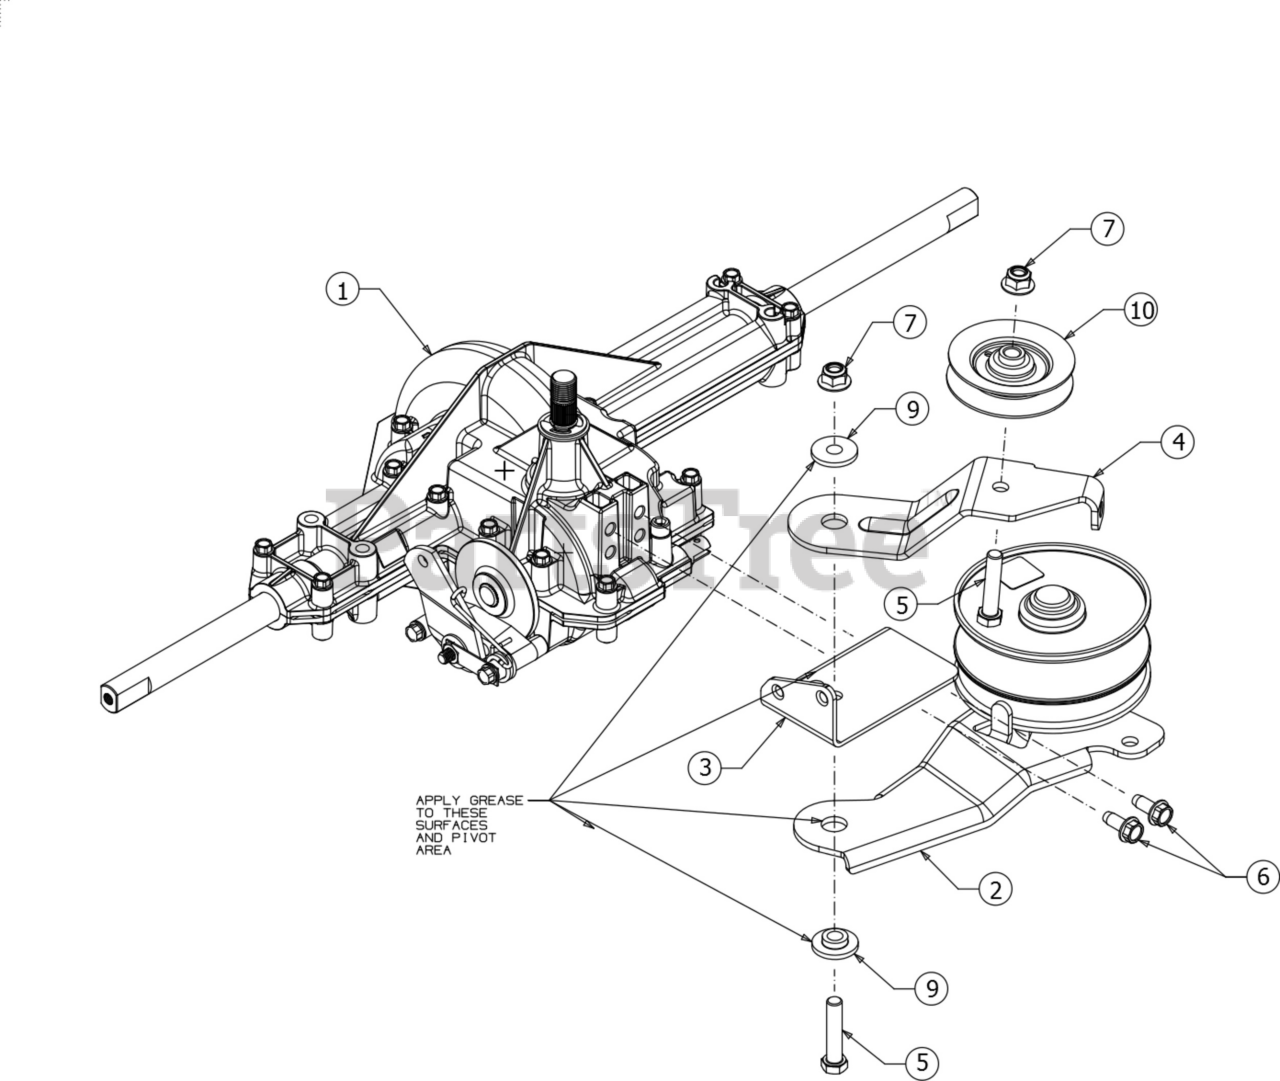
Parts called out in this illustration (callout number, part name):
1	TRANSMISSION ASSEMBLY
2	VARIABLE SPEED PULLEY ASSEMBLY
3	TRANSMISSION TORQUE BRACKET
4	IDLER BRACKET ASSEMBLY
5	HEX SCREW 3/8-16 X 1.75 GR5
6	SCREW 5/16-18 X .750
9	SHOULDER SPACER
10	V-IDLER PULLEY A X 3.06 OD
